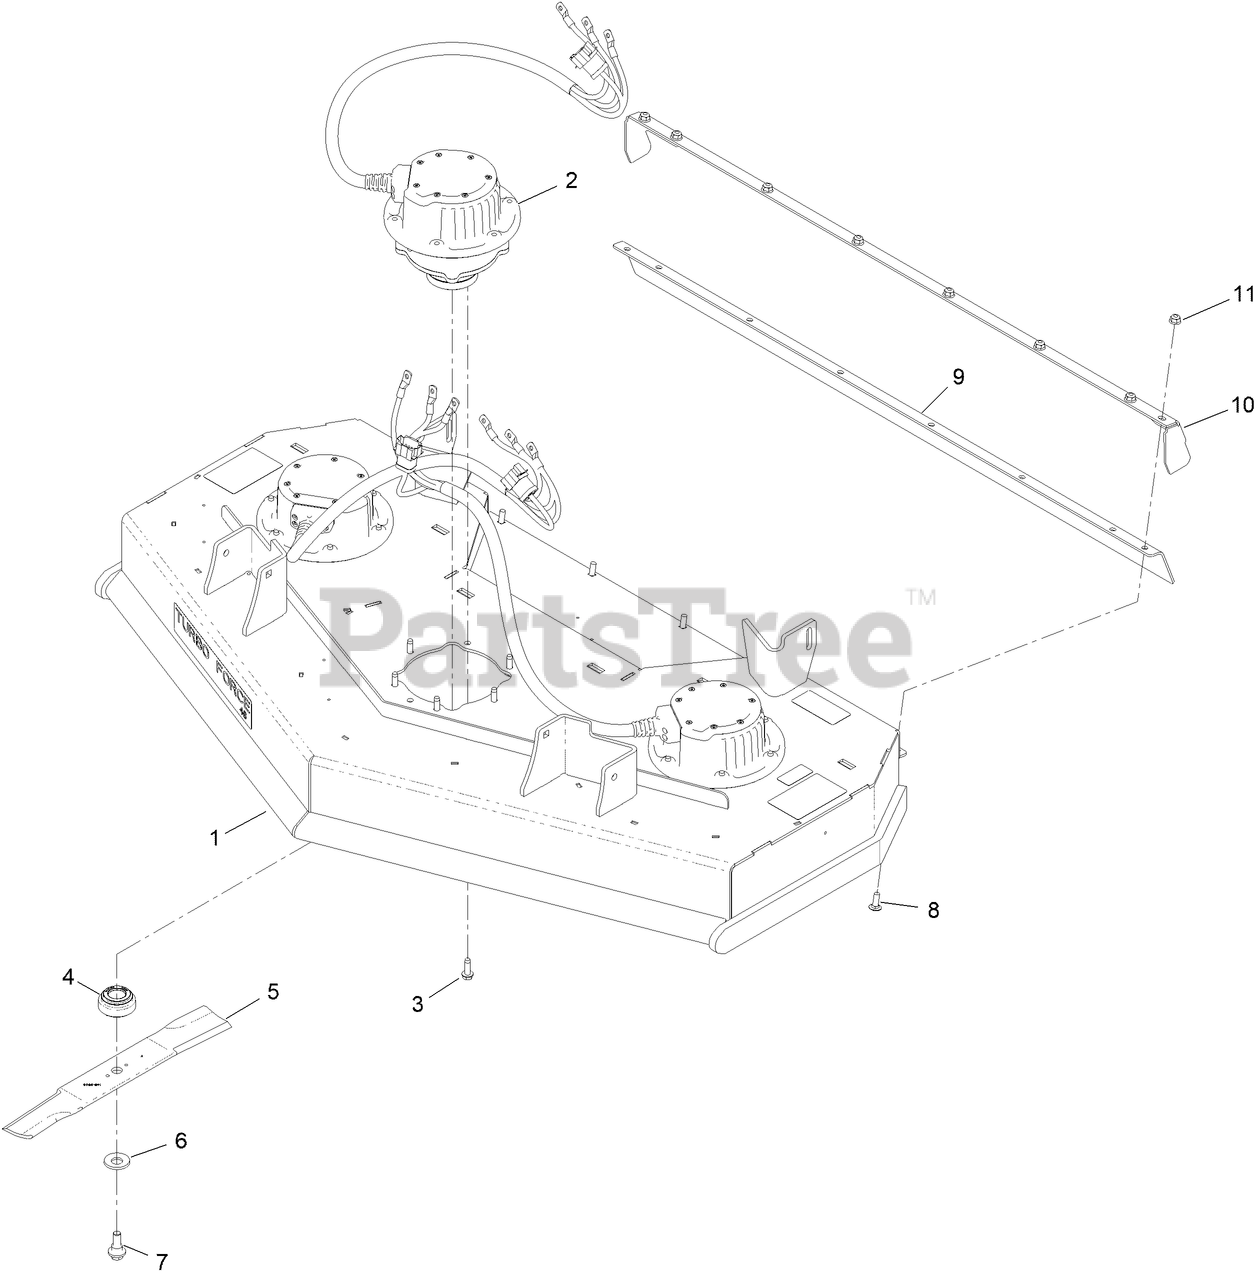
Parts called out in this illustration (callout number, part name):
1	DECK ASM, 48RD
2	MOTOR/GEN-48V,
3	SCREW-THD ROLL, HWH
4	RETAINER-BLADE
5	BLADE-16.5IN, MED SAIL
6	WASHER-BELLEVILLE
7	SCREW-SHOULDER,HWH
8	BOLT-CARR
9	GUARD-RUBBER
10	BRACKET-DEFLECTOR
11	NUT-HF, NI
